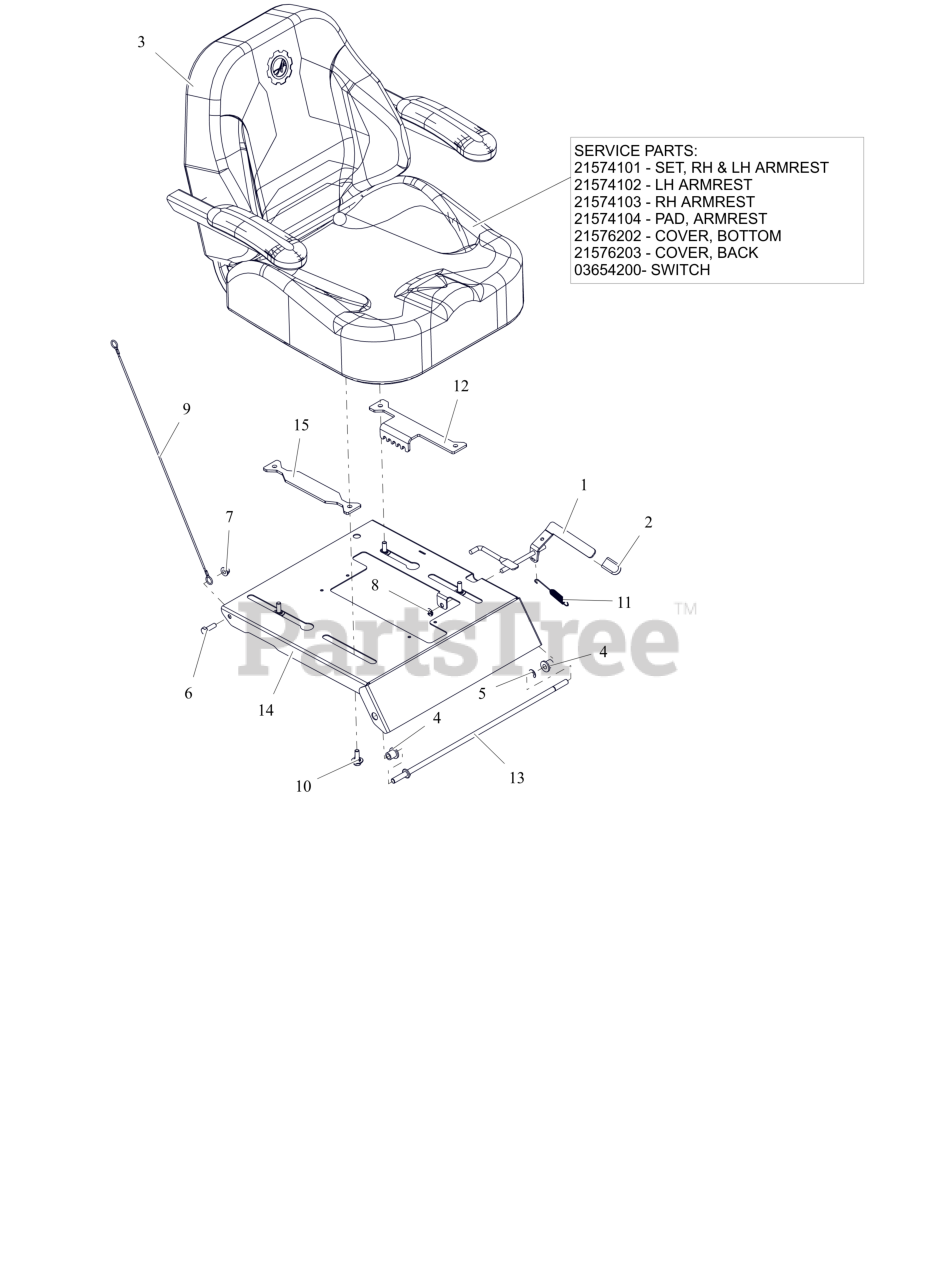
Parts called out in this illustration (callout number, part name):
1	WLDMT, ADJUSTABLE SEAT LATCH
2	GRIP, SEAT LEVER, GREY
3	SEAT- IKON XD
3	SET, RH & LH ARMREST
3	LH ARMREST
3	RH ARMREST
3	PAD, ARMREST
3	COVER, BOTTOM
3	COVER, BACK
3	SWITCH- SEAT
4	BSHG-FLG .38X.580X.667X.750
5	RG-RTNG-EXT .375X.035 TYP E
6	BLT,HEX .31-18X1.00 G5 ZCC
7	NUT,LK-NYL-FLG .31-18 G5ZC120
8	NUT-PUSH .312
9	LANYARD, SEAT CABLE .093X19.5
10	BLT, SHLDR .31-18 X .100
11	SG-TENS .043X.44X3.31 WLD 5.8
12	PLATE, ADJUSTABLE SEAT TRACK (BLACK)
13	ROD- SEAT PIVOT
14	PLATE, SEAT (ORANGE)
15	PLATE, ADJUSTABLE SEAT TRACK (BLACK)
